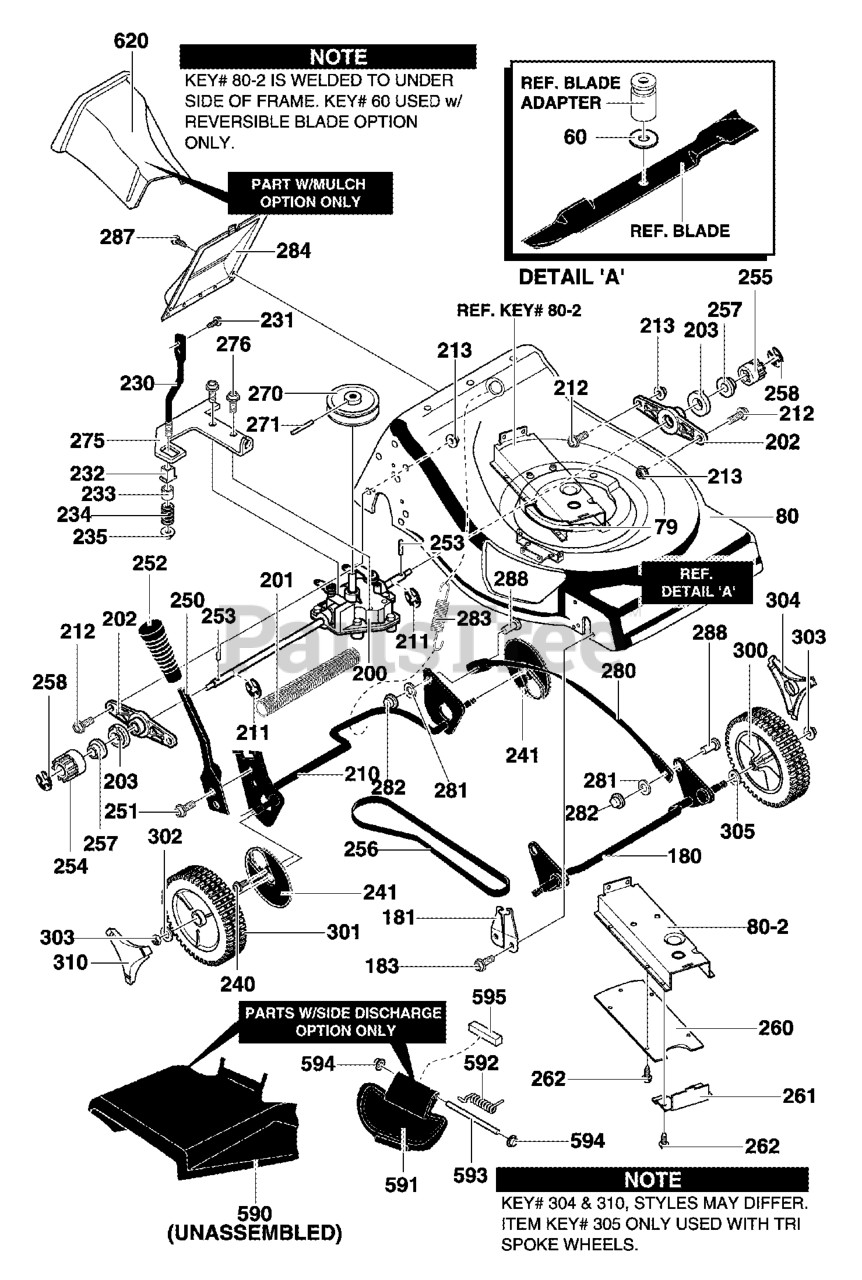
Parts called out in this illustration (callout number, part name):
60	SPACER
79	SEAL, FOAM
80	ASSY, FRAME
80-2	GUARD, BELT
180	CROSSBAR, FRONT
181	BUSHING
200	TRANSMISSION
201	SHIELD, AXLE
202	SUPPORT, AXLE
203	BEARING, LIFTER
210	ASSY, CROSSBAR
211	E-RING
212	SCREW
230	SUPPORT, SPRING
232	BUSHING
234	SPRING
235	NUT, 5/16-18
241	DUST COVER
250	LEVER, SPRING
252	KNOB, HEIGHT ADJ
253	PIN, DRIVE
254	GEAR, PINION RIGHT
255	GEAR, PINION LEFT
256	BELT, V
257	WASHER, FLAT
258	E-RING
260	COVER, BELT GUARD
261	COVER, FRONT BELT
270	PULLEY,
271	PIN, SPRING
275	BRACKET, CABLE
280	LINK, LIFTER 21
281	NUT, PUSH ON
282	PUSH ON CAP
283	SPRING, EXTENSION
284	COVER, REAR
288	PIN, CLEVIS
300	TIRE & RIM
301	WHEEL, DRIVE
302	WASHER, FLAT
304	HUB CAP
305	SPRING WASHER
310	HUB CAP
590	DEFLECTOR, CHUTE
591	COVER, MULCH
592	SPRING, TORSION
593	ROD, PIVOT
594	CAP, PUSH ON
595	SEAL, FOAM
620	PLUG, MULCHER
